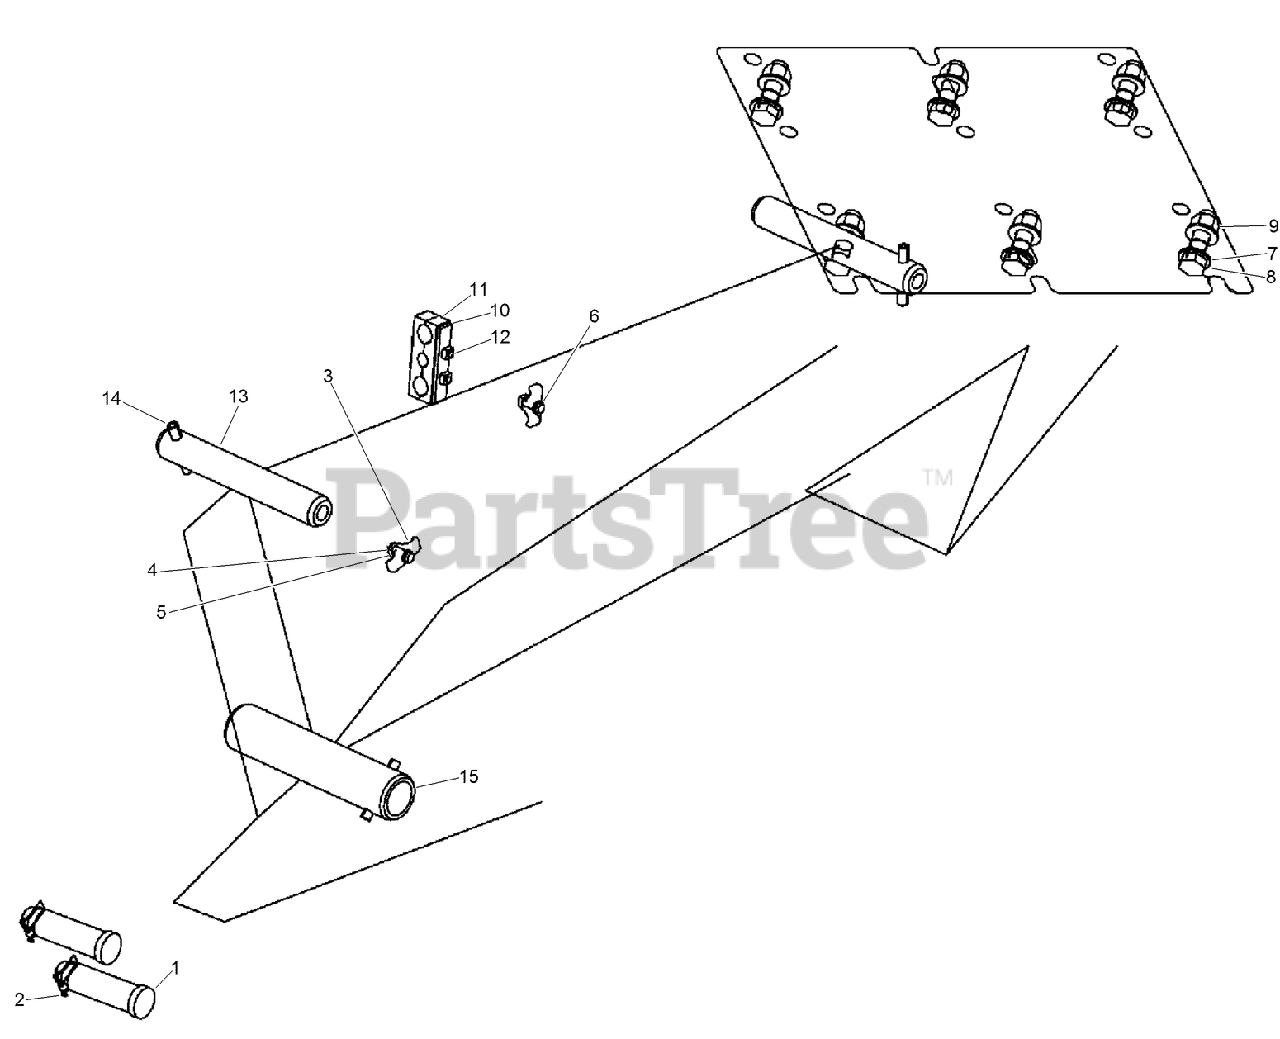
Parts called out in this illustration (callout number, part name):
1	PIN-MOUNTING, BLADE
2	PIN-KLIK
3	CLAMP-TUBE
4	BOLT-hex, 3/8 NC x 1-1/2 inch
5	NUT-SQUARE
6	WASHER-FLAT
8	SCREW-CAP, HH
11	BLOCK-CLAMP (HOSE-HYD)
12	BOLT-HH
13	PIN-PLOW ARM, UPPER
14	PIN-SPIRAL
15	PIN-PLOW ARM, LOWER REAR
